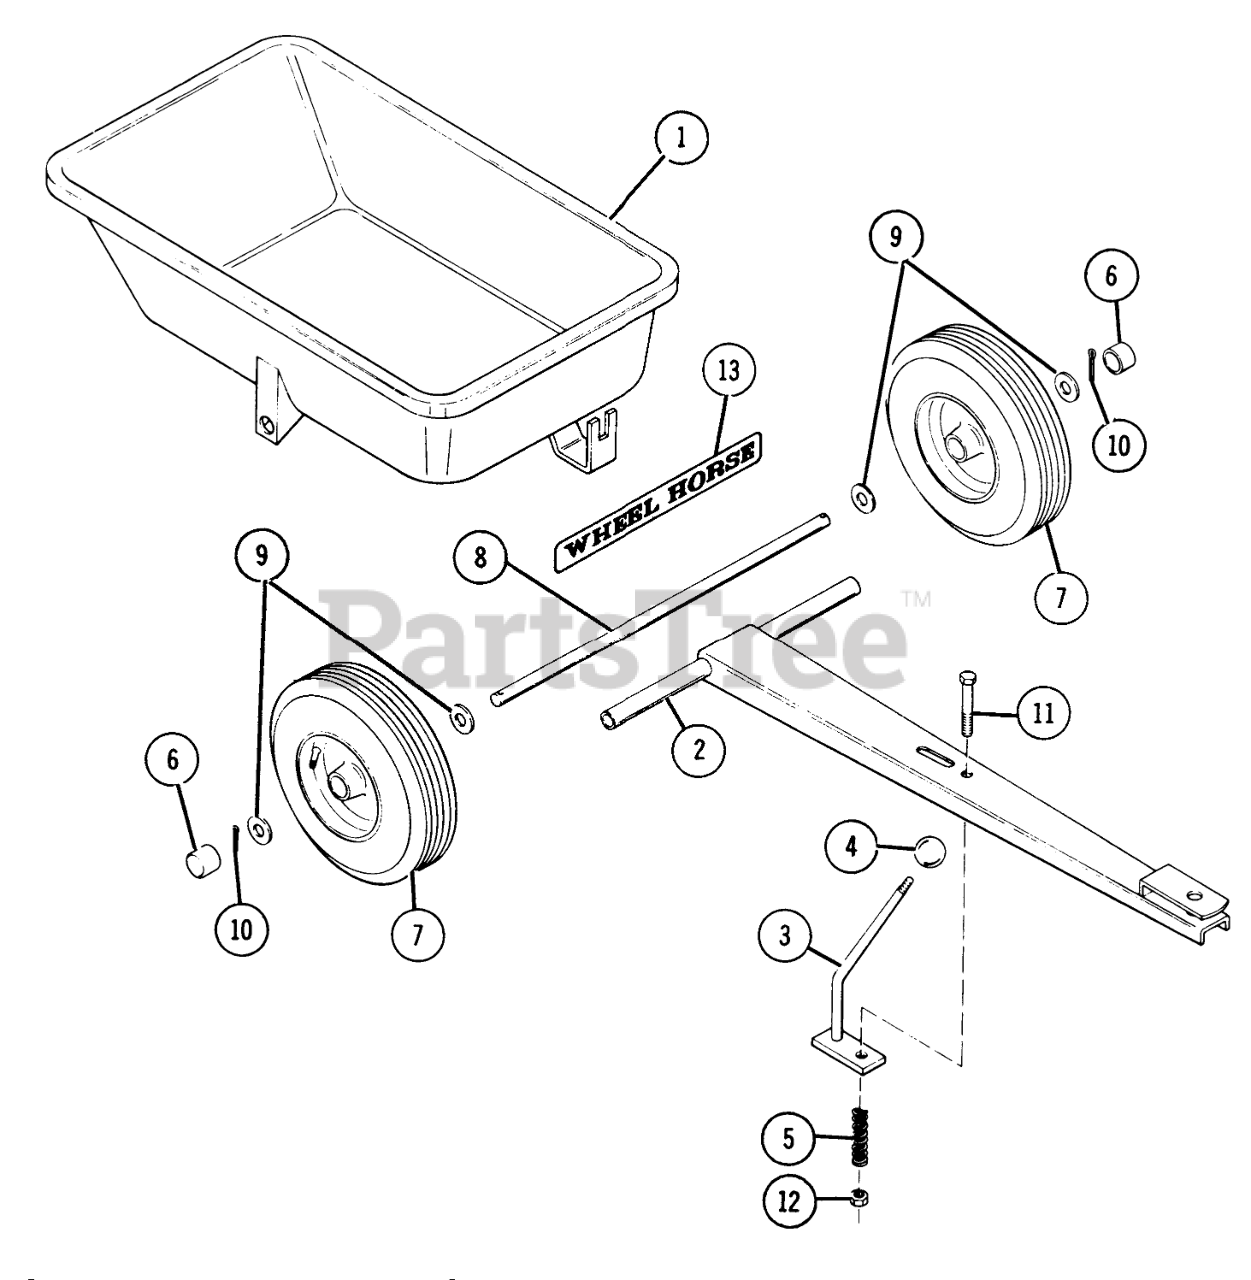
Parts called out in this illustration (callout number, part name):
1	Box Ass-y.
2	Frame Ass-y.
3	Latch Ass-y.
4	Knob
5	Spring
6	Hub Cap
7	Tire & Wheel
8	Axle
9	WASHER
10	Cotter Pin
11	HHCS
13	DECAL-WHEEL HORSE
